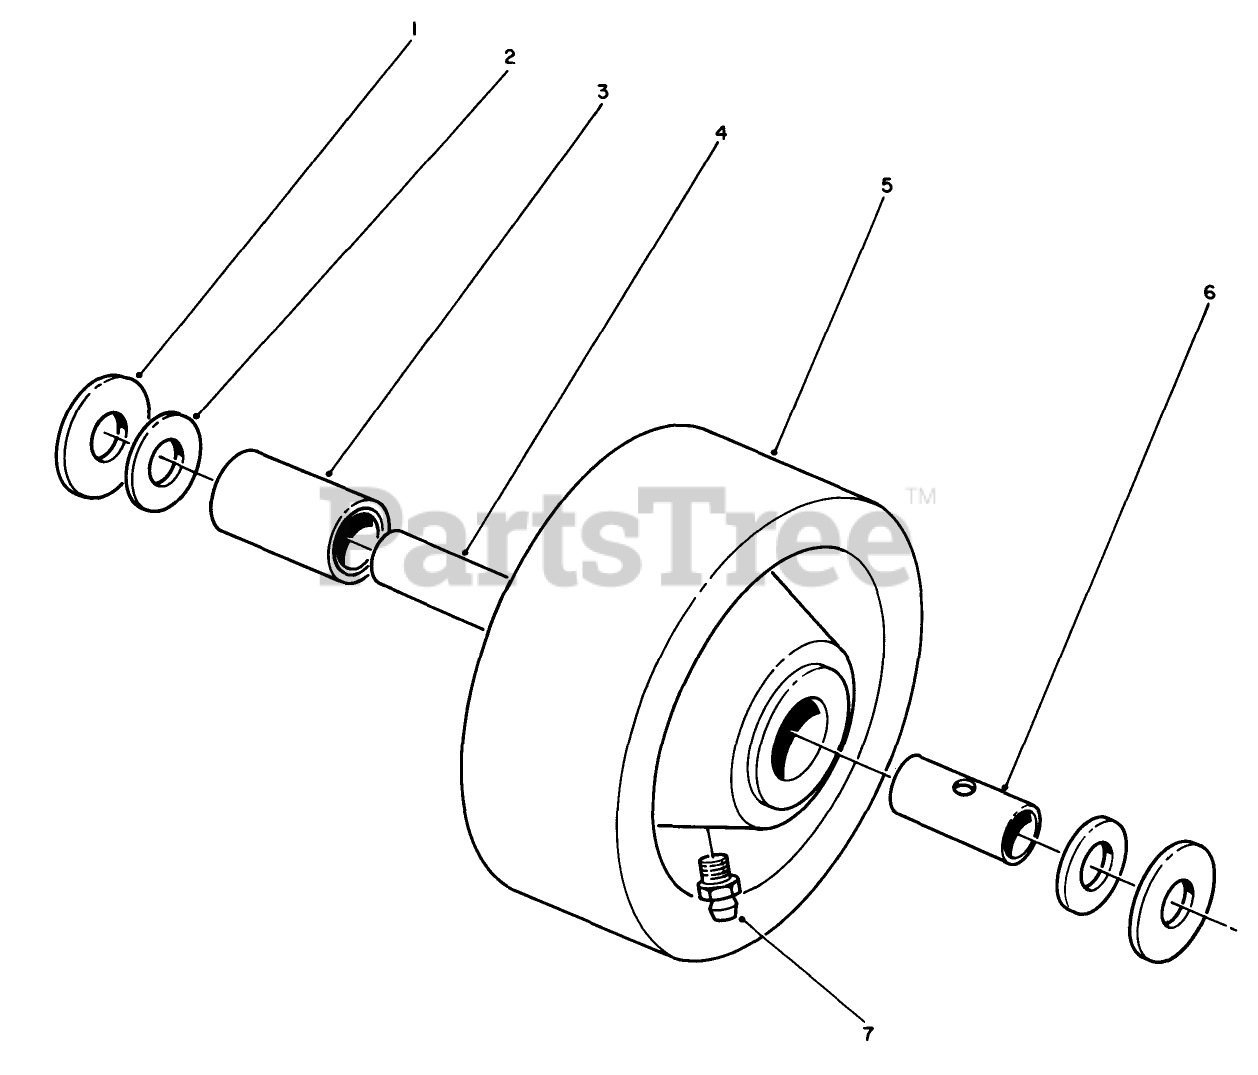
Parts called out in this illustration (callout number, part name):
1	THRUST WASHER
2	BEARING RETAINER
3	ROLLER BEARING
4	SPANNER-TIRE
5	WHEEL
6	SPANNER BUSHING
7	FITTING-GREASE
